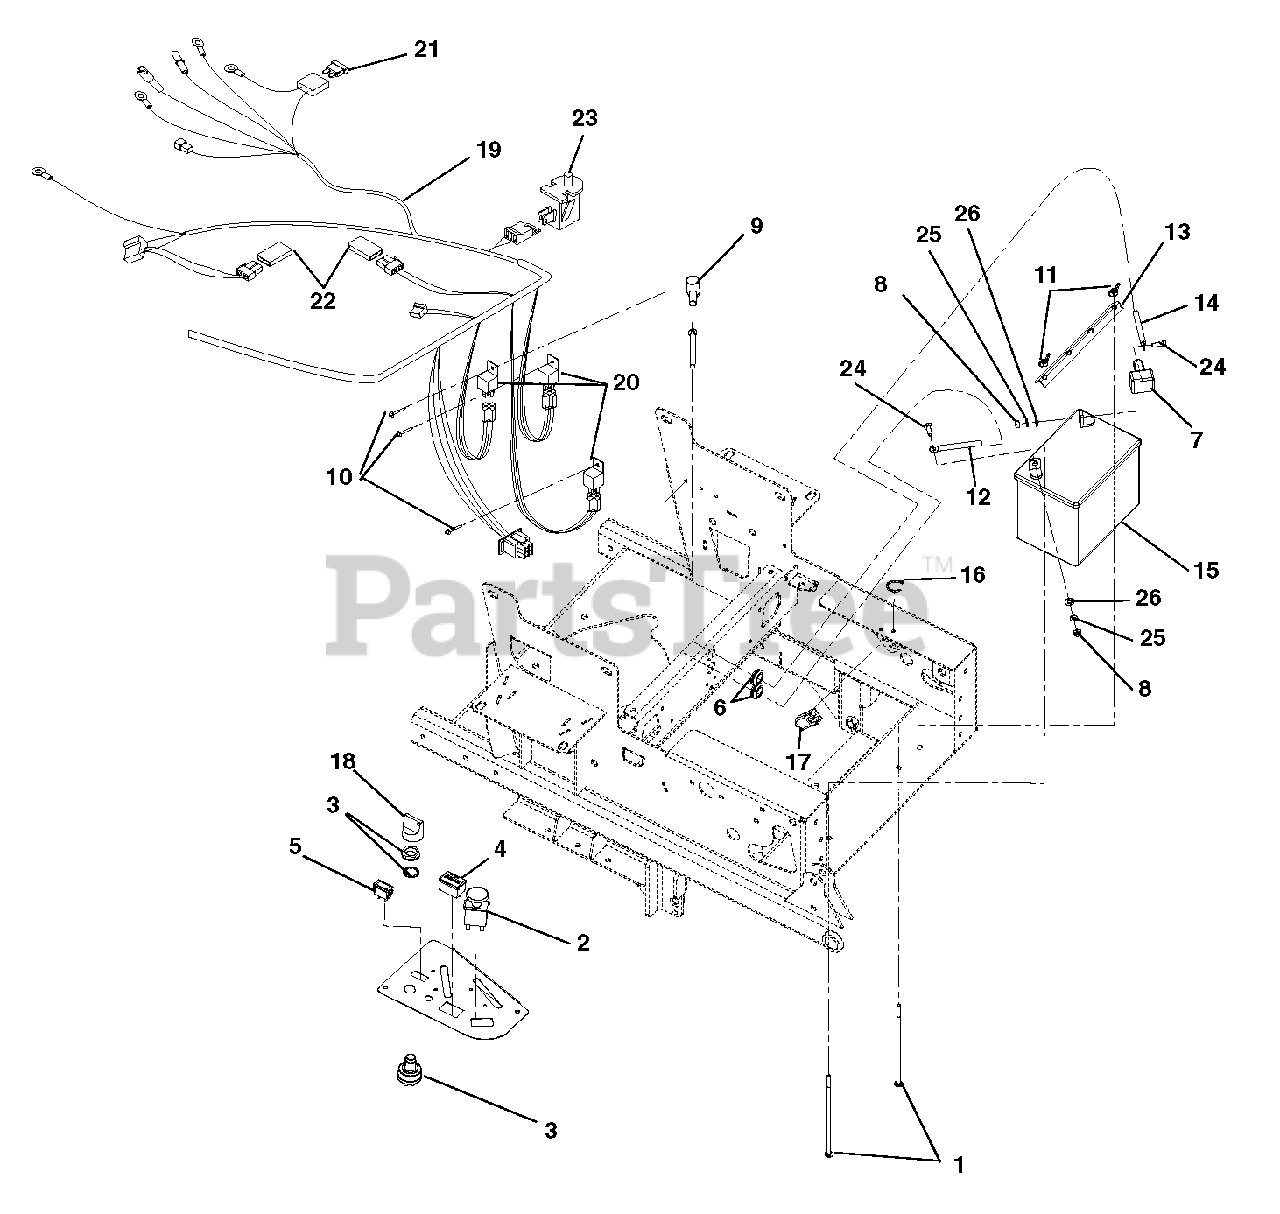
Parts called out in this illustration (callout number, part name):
1	Bolt, Round Head Square Neck .25-20 x 7.50
2	Switch, Clutch
3	Switch, Ignition
4	Hour Meter w/Maintenance
5	Light, Indicator
6	Grommet, Rubber 5/8 ID/1.13
7	Insulator
8	Nut, Hex .25-20
9	Battery Terminal Boot, Red
10	Rivet, .25 Nylon Panel
11	Nut, Locking Wing .250-20
12	Ground Cable .31 x 22.00 x .31
13	Hold Down
14	Cable, Positive Battery 26.00"
15	Exide Battery Sealed Maintenance Free U1-250
16	Cable Tie
17	Switch, Snap In- N.O./N.O.
18	Key, with Shield
19	Harness, Wire- IZ, CZ, 100I
20	Relay,Sealed w/Diode
21	Fuse, 30 AMP.
22	Diode, Connector Shell
23	Switch, Snap Mounting (N.O.)
24	Bolt, Hex .25-20 x .75 Grade 5
25	Washer, Locking .25 x .062 Regular
26	Washer, Flat-STL.281 x .62 x .065
